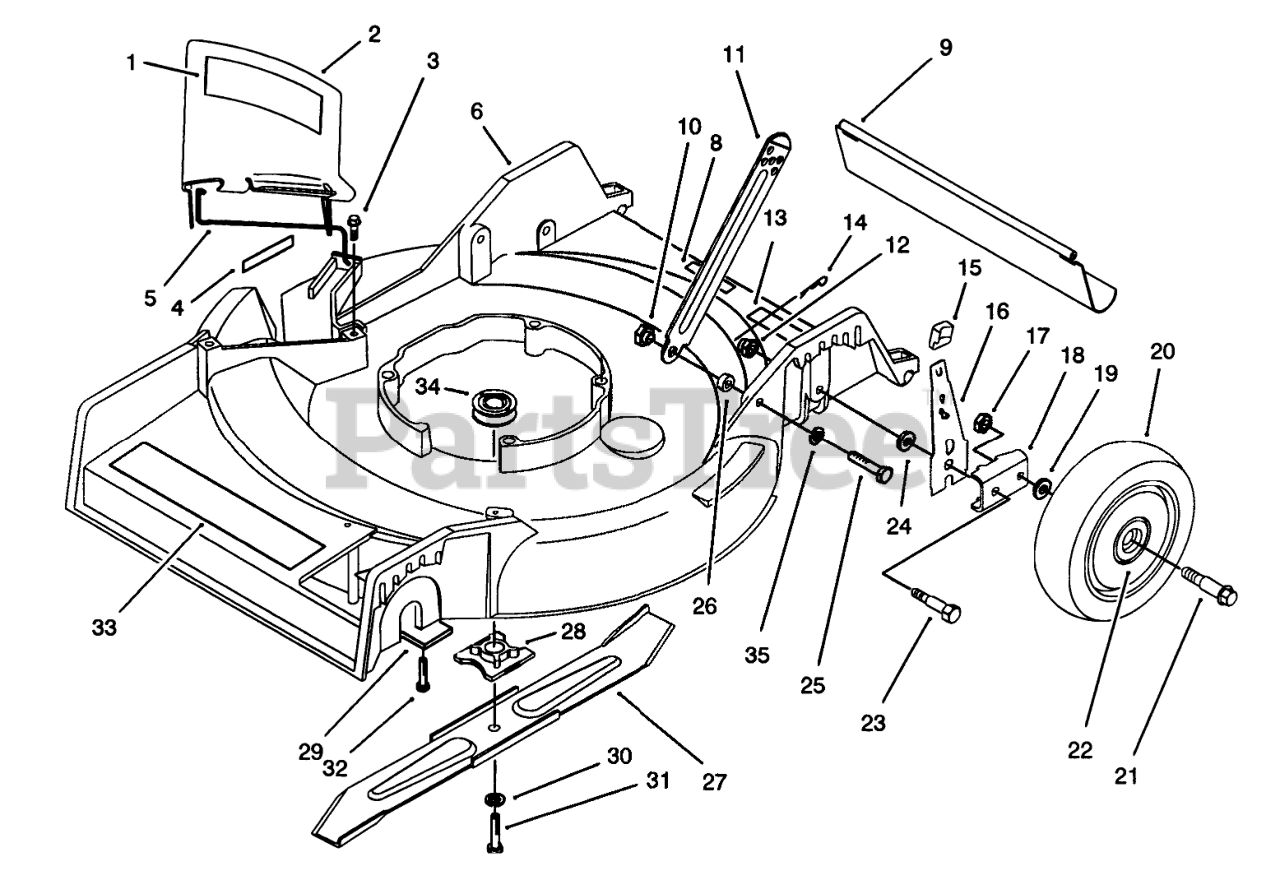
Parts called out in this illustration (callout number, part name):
1	DECAL - DANGER DEFL
2	Deflector (Incl. Ref. #1 & 5)
3	SCREW-HWH
4	DANGER DECAL
5	SPRING HINGE
6	Housing (Incl. Ref. #4)
8	DECAL FRENCH REGUL.
9	SHIELD - TRAILING
10	HANDLE PIVOT NUT
11	HANDLE LATCH
12	HANDLE PIVOT NUT
13	Decal-Noise
14	PIN-COTTER, HAIR
15	KNOB-ARM
16	SPRING ARM ASSEMBLY
17	NUT-LOCK
18	HP PIVOT ARM ASM
19	WASHER
20	Wheel & Tire Assembly (Incl. Ref. #22)
21	WHEEL BOLT
22	BUSHING
23	PIVOT SCREW
24	PIVOT WASHER
25	SCREW-HH
26	SPACER
27	Blade
28	BLADE RETAINER
29	FRONT SHIELD
30	WASHER-LOCK
31	SCREW-HH
32	SCREW-HWHTF
33	DECAL - SP DECK
34	PULLEY-DRIVER
35	WASHER-LOCK
